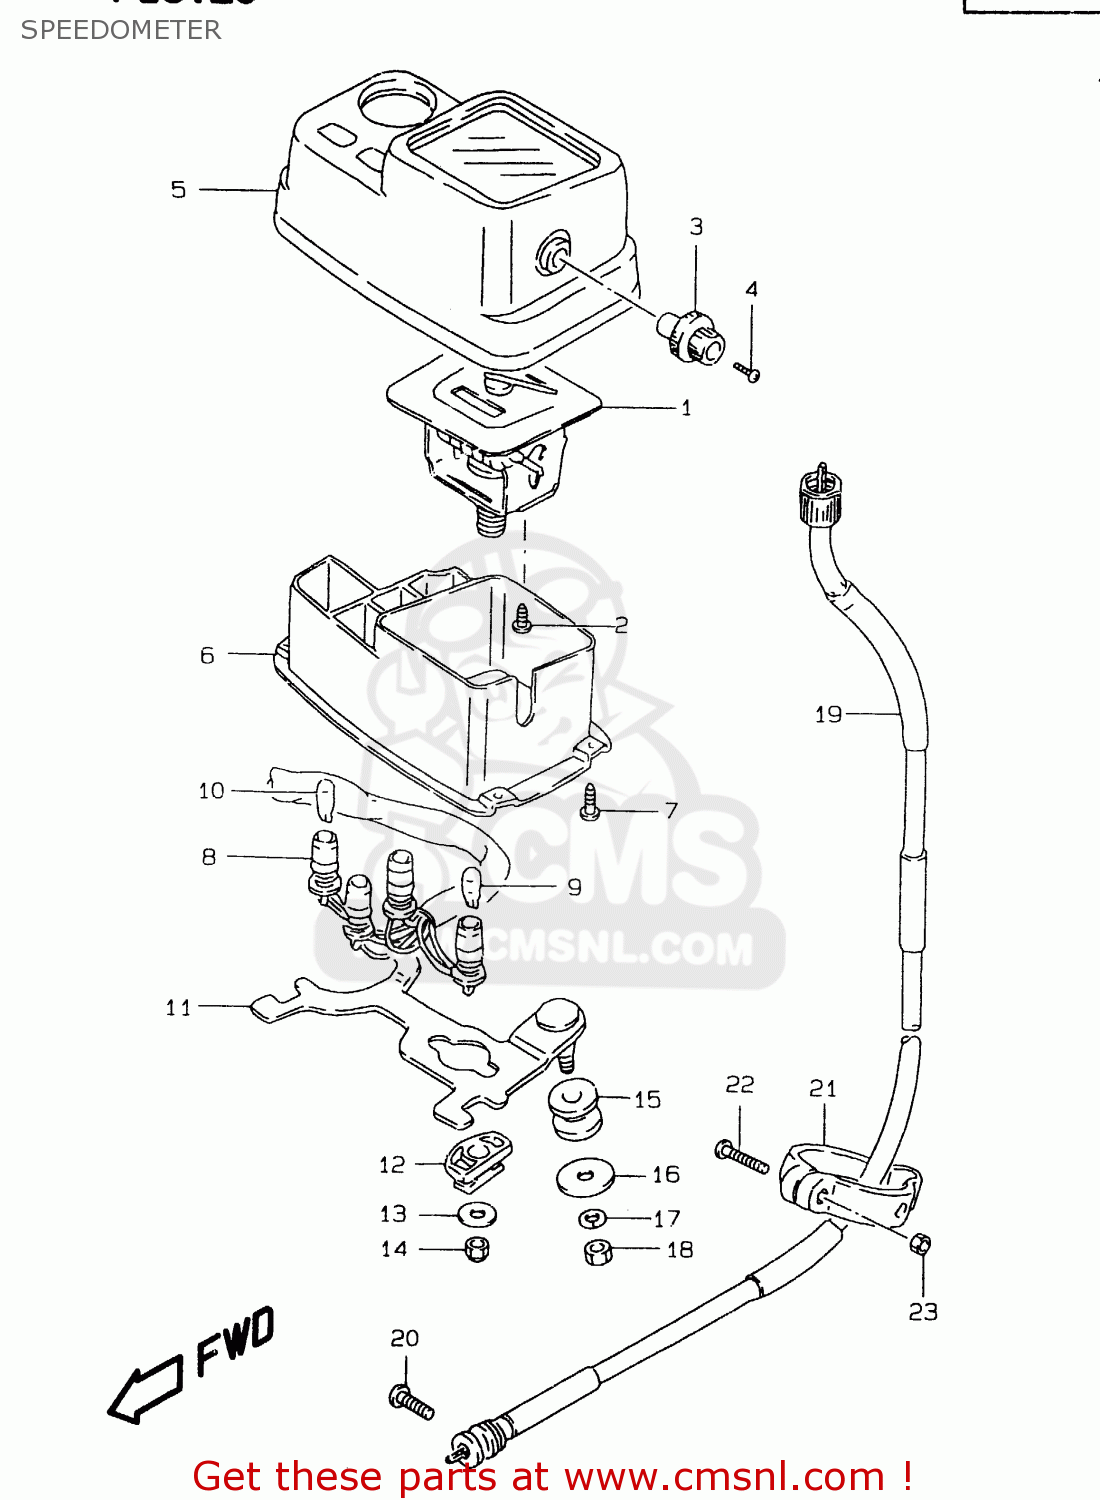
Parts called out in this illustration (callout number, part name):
1	SPEEDOMETER
2	SCREW
3	KNOB,TRIP
4	SCREW(2X6)
5	HOOD,METER
6	CASE,METER
7	SCREW
8	SOCKET ASSY
9	BULB(12V3.4W,T10)
10	BULB(12V1.7W,T10,WB121)
11	BRACKET,METER
12	CUSHION
13	WASHER (5.5X16X1.2)
14	NUT
15	CUSHION
16	WASHER
17	LOCK WASHER
18	NUT 6MM
19	CABLE ASSY,SPEEDOMETER
20	SCREW
21	CLAMP,SPEEDOMETER CABLE
22	SCREW
23	NUT
